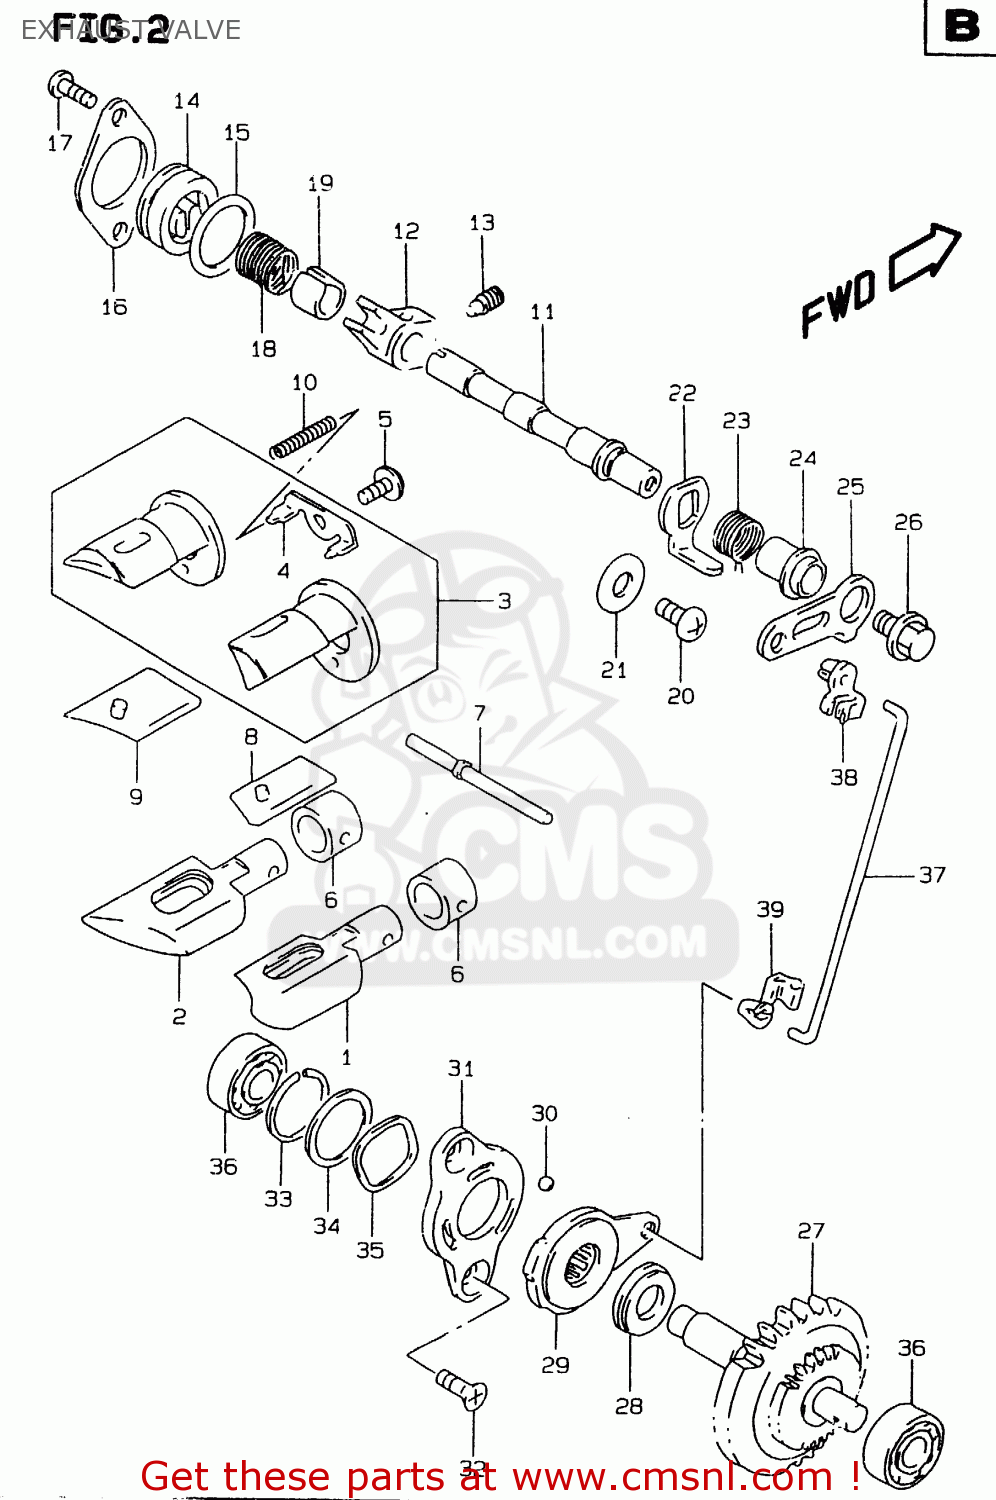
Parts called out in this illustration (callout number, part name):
1	VALVE,EXHAUST,LOWER,RIGHT
2	VALVE,EXHAUST LOW,L
3	GUIDE SET,EXHAUST VALVE
4	STOPPER,EXHAUST VALVE NO.2
5	SCREW 5X12
6	SPACER,EXHAUST VALVE
7	PIN,EXHAUST VALVE 48.5MM
8	VALVE,EXHAUST MIDDLE,R
9	VALVE,EXHAUST MIDDLE,L
10	SPRING
11	SHAFT,EXHAUST VALVE
12	ARM,EXHAUST VALVE SHAFT
13	SCREW(6X10)
14	CAP,EXHAUST VALVE
15	O RING(D:1.9,ID:22.6)
16	RETAINER,EXHAUST VALVE
17	BOLT
18	SPRING
19	SPACER,EXHAUST VALVE SPRING
20	BOLT
21	WASHER
22	LEVER,EXHAUST VALVE NO.2
23	SPRING
24	SPACER,EXHAUST VALVE
25	LEVER,EXHAUST VALVE NO.1
26	BOLT(5X12)
27	GOVERNOR ASSEMBLY,EXHAUST
28	BEARING(10X22X2.8)
29	ACTUATOR,EXHAUST VALVE
30	BALL
31	STARTER,EXHAUST VALVE ACTUATOR
32	SCREW(5X10)
33	CIRCLIP
34	SHIM(19.1X25X0.3)
35	WASHER
36	BEARING(8X22X7)
37	ROD,EXHAUST VALVE
38	BUSH,EXHAUST VALVE ROD NO.1
39	BUSH,EXHAUST VALVE ROD NO.2
